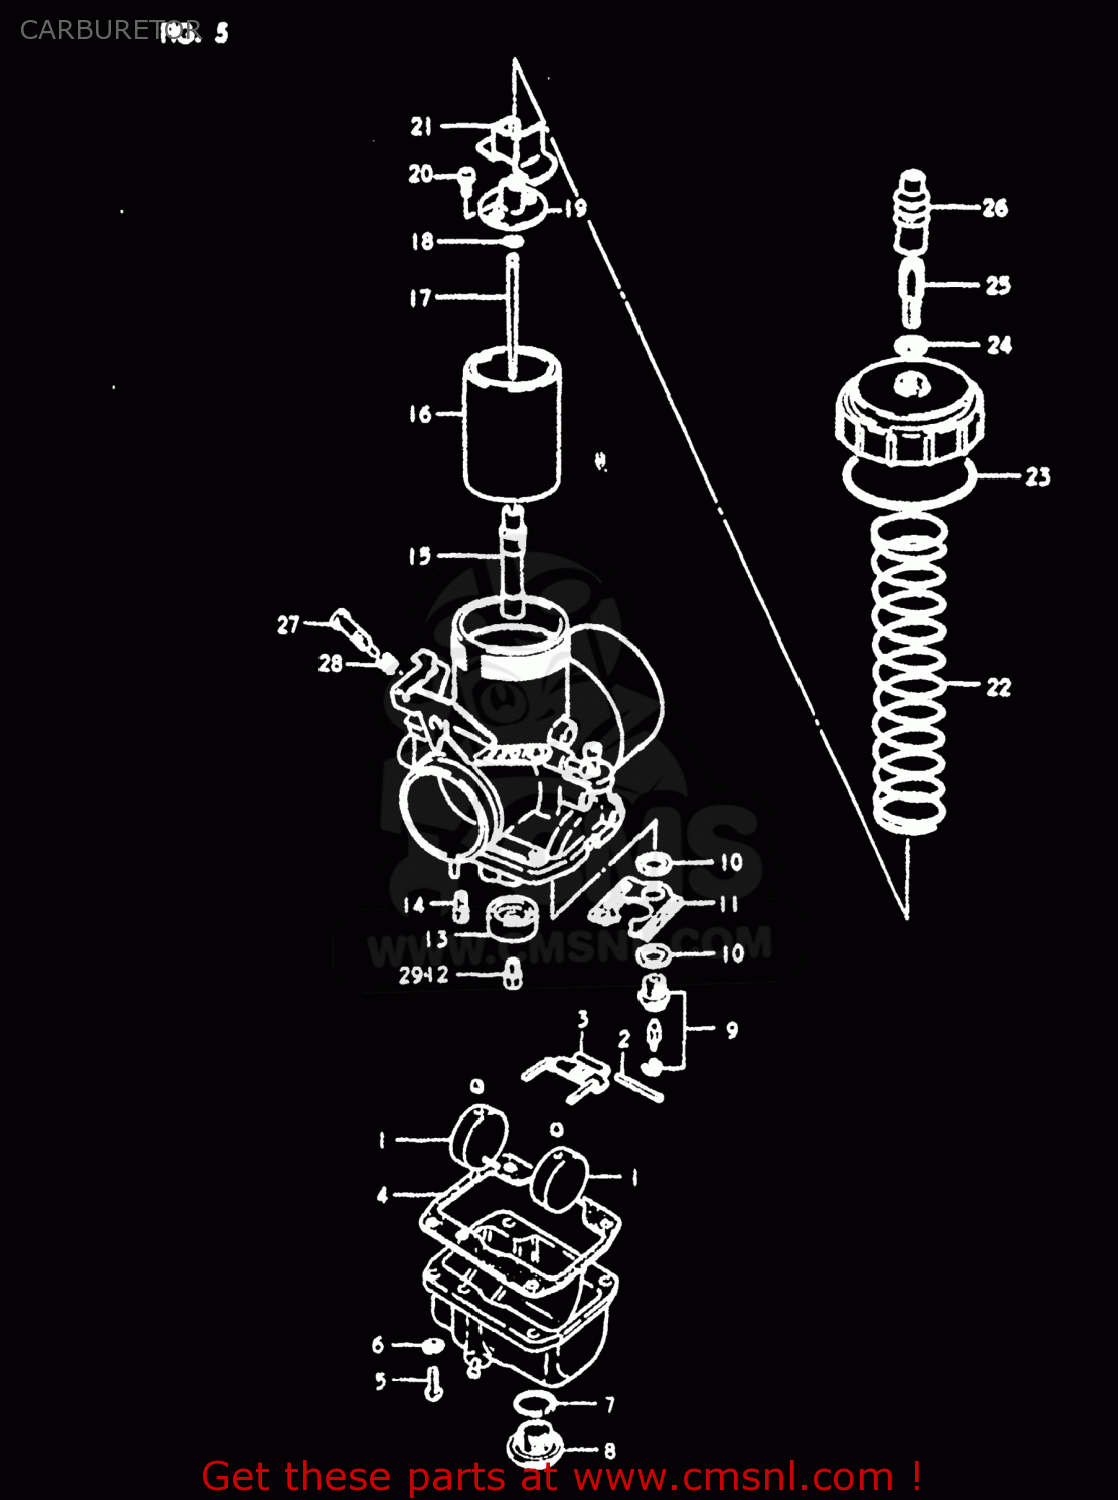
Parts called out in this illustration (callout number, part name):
1	FLOAT
2	PIN,FLOAT
3	ARM,FLOAT
4	GASKET,FLOAT CAHMBER (NAS)
5	SCREW
6	LOCK WASHER
7	O-RING
8	PLUG
9	VALVE ASSEMBLY,NEEDLE
10	GASKET,MAIN JET HOLDER (NAS)
11	PLATE
12	JET
13	RING
14	JET,PILOT
15	JET,NEEDLE
16	VALVE,THROTTLE
17	JET,NEEDLE(6FJ6-3)
18	CLIP
19	CONNECTOR
20	SCREW
21	COVER,HOLDER
22	SPRING,THROTTLE VALVE RETURN
23	GASKET,MIXING CHAMBER (NAS)
24	NUT
25	ADJUSTER,CABLE
26	CAP,CABLE ADJUSTER
27	SCREW,PILOT AIR
28	SPRING
29	JET
